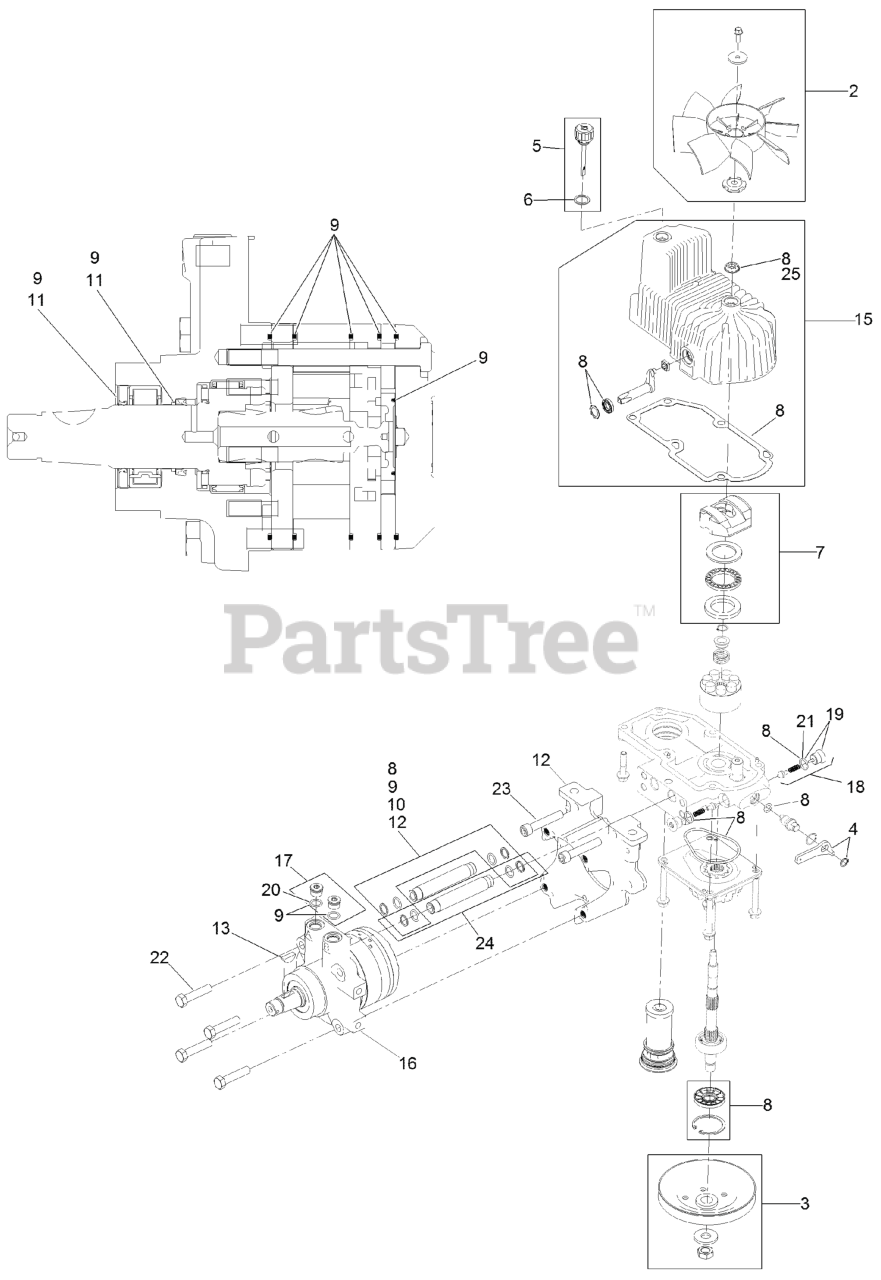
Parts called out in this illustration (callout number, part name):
2	FAN KIT
3	PULLEY KIT
4	HANDLE-BYPASS VALVE, HYDRO
5	DIPSTICK-HYDRO W/GASKET
6	GASKET-DIPSTICK, HYDRO
7	SWASH BLOCK KIT
8	PUMP SEAL KIT
9	MOTOR SEAL KIT
10	TUBE SEAL KIT
11	OUTPUT SHAFT SEAL KIT
12	NOSE CUP-UHT
13	KEY-WOODRUFF
15	HOUSING-HYDRO, LH
16	MOTOR-HYDRAULIC LH 240CC
17	MAGNETIC PLUGS SERVICE KIT
18	CHECK VALVE ASM
19	PLUG-CHECK (W/O-RING)
21	O-RING-CHECK VALVE
22	SCREW HH
23	SCREW-HSH
24	HYDRAULIC TUBE KIT
25	SEAL-FAN DRIVE
26	PULLER-PULLEY
27	ROTATING KIT
